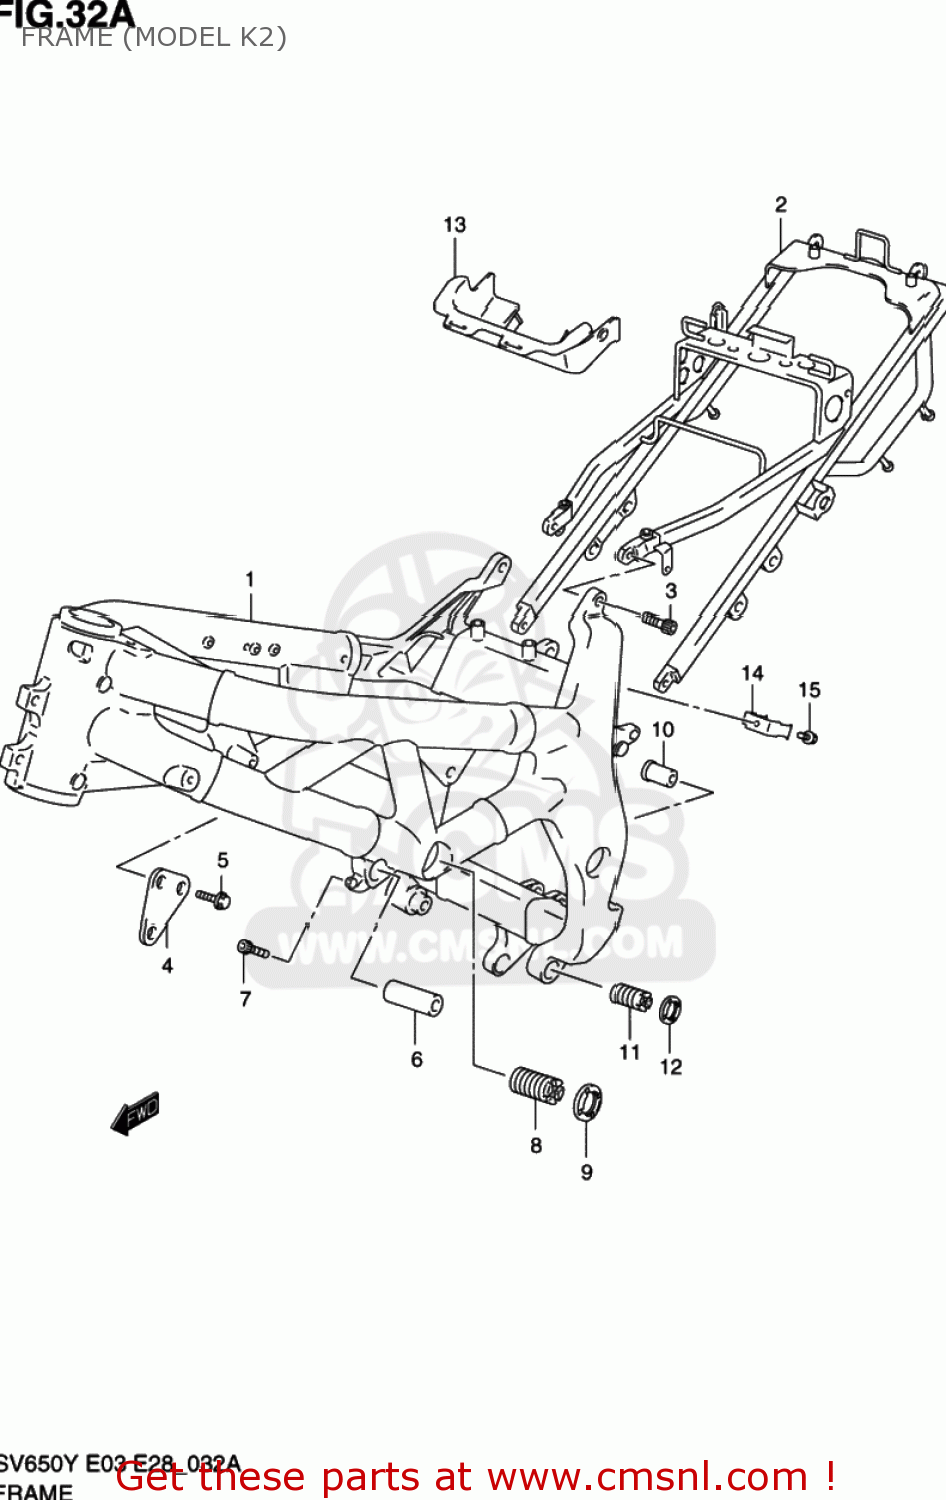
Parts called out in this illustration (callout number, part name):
1	FRAME(SILVER)
2	RAIL,SEAT
3	BOLT
4	PLATE,ENG HEAD MTG FR,R
5	BOLT
6	SPACER,ENG HEAD MTG
7	BOLT
8	BOLT,CRANK CASE ADJUST
9	NUT,CRANKCASE ADJUST
10	SPACER,MOUNTING RR UPR,R
11	BOLT,CRANKCASE ADJUST
12	NUT,CRANK CASE ADJUST BOLT
13	HOLDER,ELECTRIC PARTS
14	PLATE,RELAY FITTING
15	BOLT
